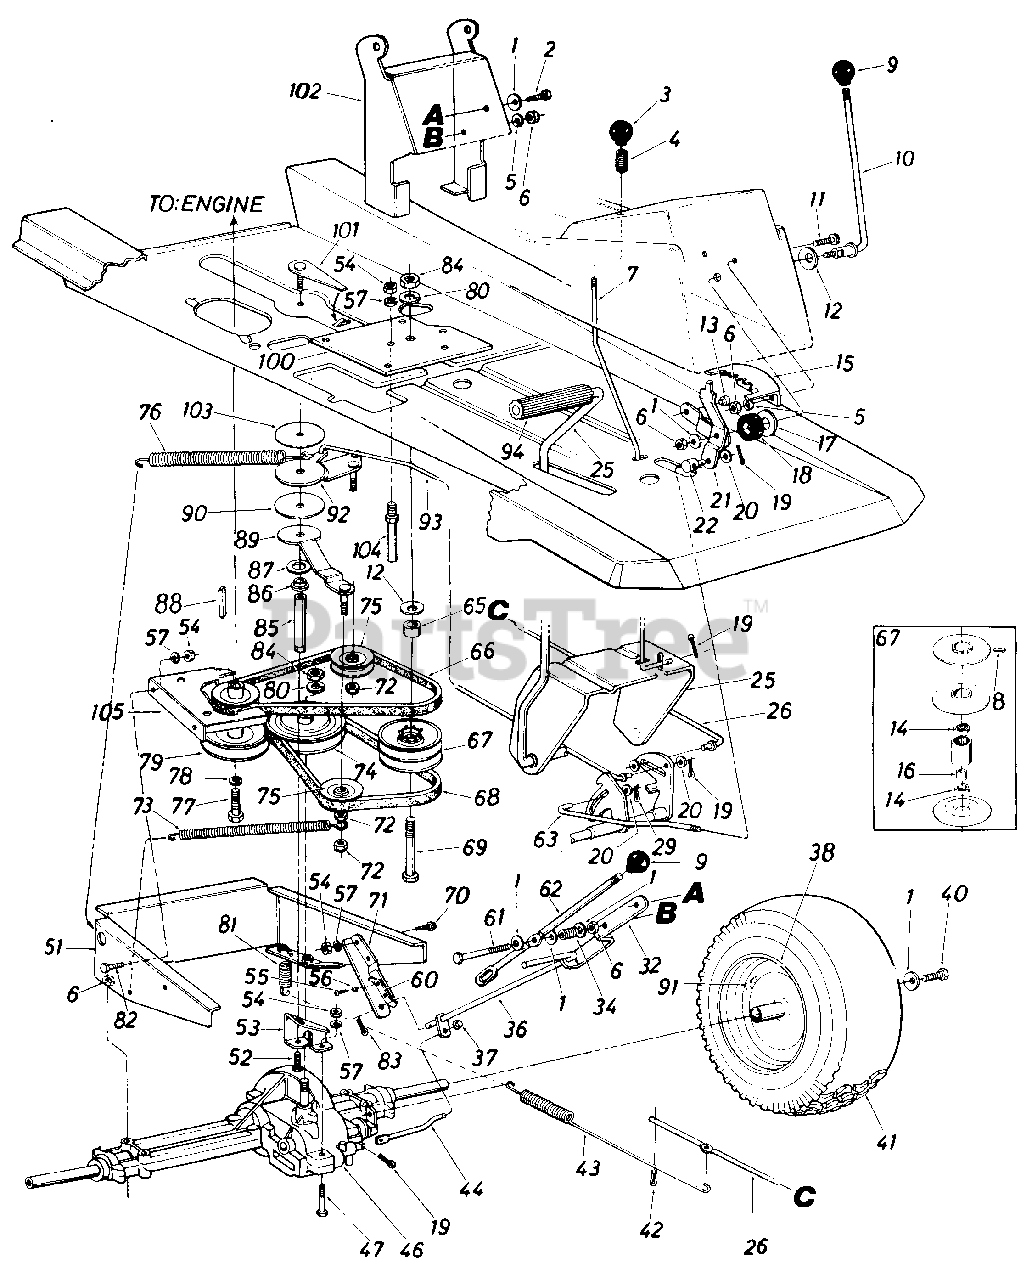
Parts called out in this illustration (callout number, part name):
1	Bell-Wash..345" I.D. x .88" O.D.
2	Hex Wash. Hd. AB-Tap Scr. 1/4 x.62" Lg.
4	Compression Spring
5	L-Wash. 5/16" I.D.*
6	Hex Nut 5/16-18 Thd.*
7	Brake Locking Rod
8	Spring Pin Spir. 5/32" Dia. x.62" Lg.
9	Gear Shift Knob
10	Speed Control Lever
11	Truss Mach. Scr. 5/16-18 x .75" Lg.*
12	Bell-Wash. .505" I.D. x 1.00"
14	Ball Brg. .50" I.D. x 1.38"
15	Index Bracket
16	Spacer.50" I.D. x .69" O.D. x 1.38" Lg.
17	Fl-Wash. 1/2" I.D. x 1.50"
18	Rubber Wash. .50" I.D. x 1.25" O.D.
19	Cotter Pin 1/8 x 1.00" Lg.*
20	Fl-Wash. .344" I.D. x .688"
21	Speed Control Lever Brkt. Ass'y.
22	Ferrule Engagement
25	Clutch-Brake Pedal Ass'y.
29	Intern. Cotter Pin 5/16" Dia.
32	Shift Lever Brkt.
34	Spring
36	Shift Lever Ass'y.
37	Cap Speed Nut 1/4" Rod
38	Rear Wheel Rim Only
40	Hex L-Bolt 5/16-24 x .75" Lg.
41	Rear Wheel Ass'y. Comp.
42	Cot-Pin 1/8" Dia. x 1.25
43	Ext. Spring .75" O.D. x 17.0" Lg.
44	Shift Rod
46	Transaxle Comp.
47	Hex Bolt 1/4-20 x 1.75" Lg.*
53	Torque Rod Bracket
54	Hex Nut 1/4-20 Thd.*
55	C-Sink AB S-Tap Scr. #8 x .50"
56	Push-In Nut #10
57	L-Wash. 1/4" I.D.*
60	Spring Switch
61	Hex Bolt 5/16-18 x 2.25" Lg.*
62	Upper Shift Lever
63	Speed Control Rod
65	Spacer.501" I.D. x .750" O.D. x .775
66	"V"-Belt 5/8" L x 35" Lg.
67	Variable Speed Pulley Ass'y.
68	"V"-Belt 5/8" L x 38" Lg.
69	Hex Bolt 1/2-13 x 4.0" Lg.*
70	Hex Bolt 1/4-20 x .62" Lg.*
71	Shift Lever Support
72	Hex Ins. L-Nut 3/8-24 Thd.
73	Extension Spring
74	5/8" V-Pulley 6.0" O.D.
75	"V"-Belt Idler 3.06" O.D.
76	Extension Spring .99" O.D. x 8.0" Lg.
77	Hex Bolt 7/16-20 x 1.0" Lg.*
78	L-Wash. 7/16" I.D.*
79	Engine Pulley
80	L-Wash. 1/2" I.D.*
81	Brake Return Ext. Spring
82	Hex Bolt 1/4-20 x .75" Lg.*
83	Cotter Pin 3/32" Dia. x .75" Lg.
84	Hex Nut 1/2-13 Thd.*
85	Torque Rod 3.835" Lg.
86	Flange Bearing .378
87	Fl-Wash. .640" I.D. x 1.24"
88	Sq. Key 1/4" x 2.00" Lg.*
89	Idler Bracket Ass'y.
90	Thrust Wash. .635" I.D. x 3.50" O.D.
91	Air Valve
92	Idler Bracket Ass'y.
94	Foot Pad
100	Mounting Bracket Variable Speed Pulley
103	Thrust Wash. .385" I.D. x 3.50" O.D.
104	Belt Guard Pin 1/4" Dia. x 1.68" Lg.
105	Upper Engine Belt Guard
